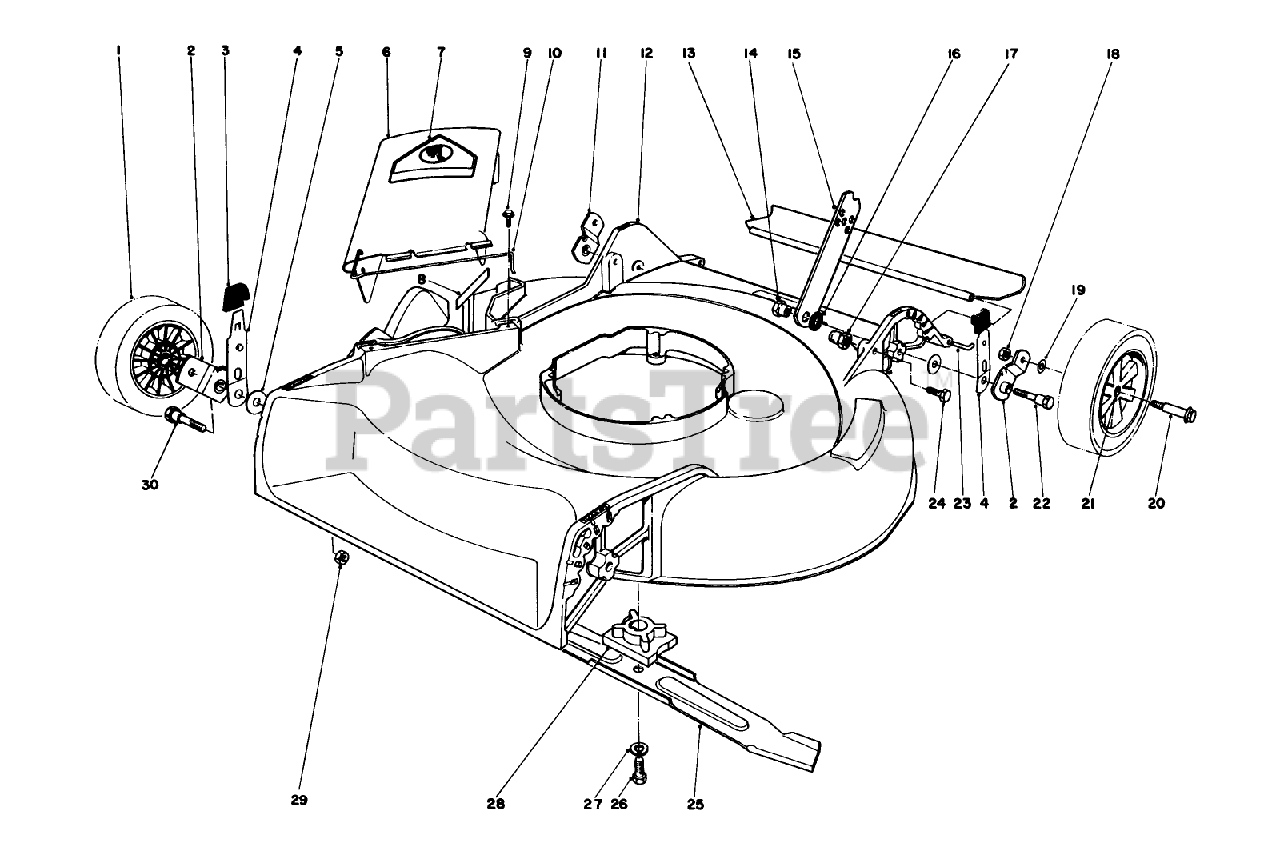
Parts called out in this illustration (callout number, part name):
1	WHEEL TIRE ASM 8 IN
3	KNOB-ARM
4	SPRING ARM ASM
5	WASHER-PIVOT
7	DECAL-DANGER
9	SCREW-HWH
14	HANDLE PIVOT NUT
15	HANDLE LATCH
16	SPACER
17	HANDLE PIVOT NUT
18	NUT-LOCK
19	WASHER
20	WHEEL BOLT
21	BUSHING
22	PIVOT SCREW
23	SHIELD ROD
24	SCREW-HH
26	SCREW-HH
27	WASHER-LOCK
28	BLADE RETAINER
29	NUT-LOCK, NI
30	PIVOT SCREW
